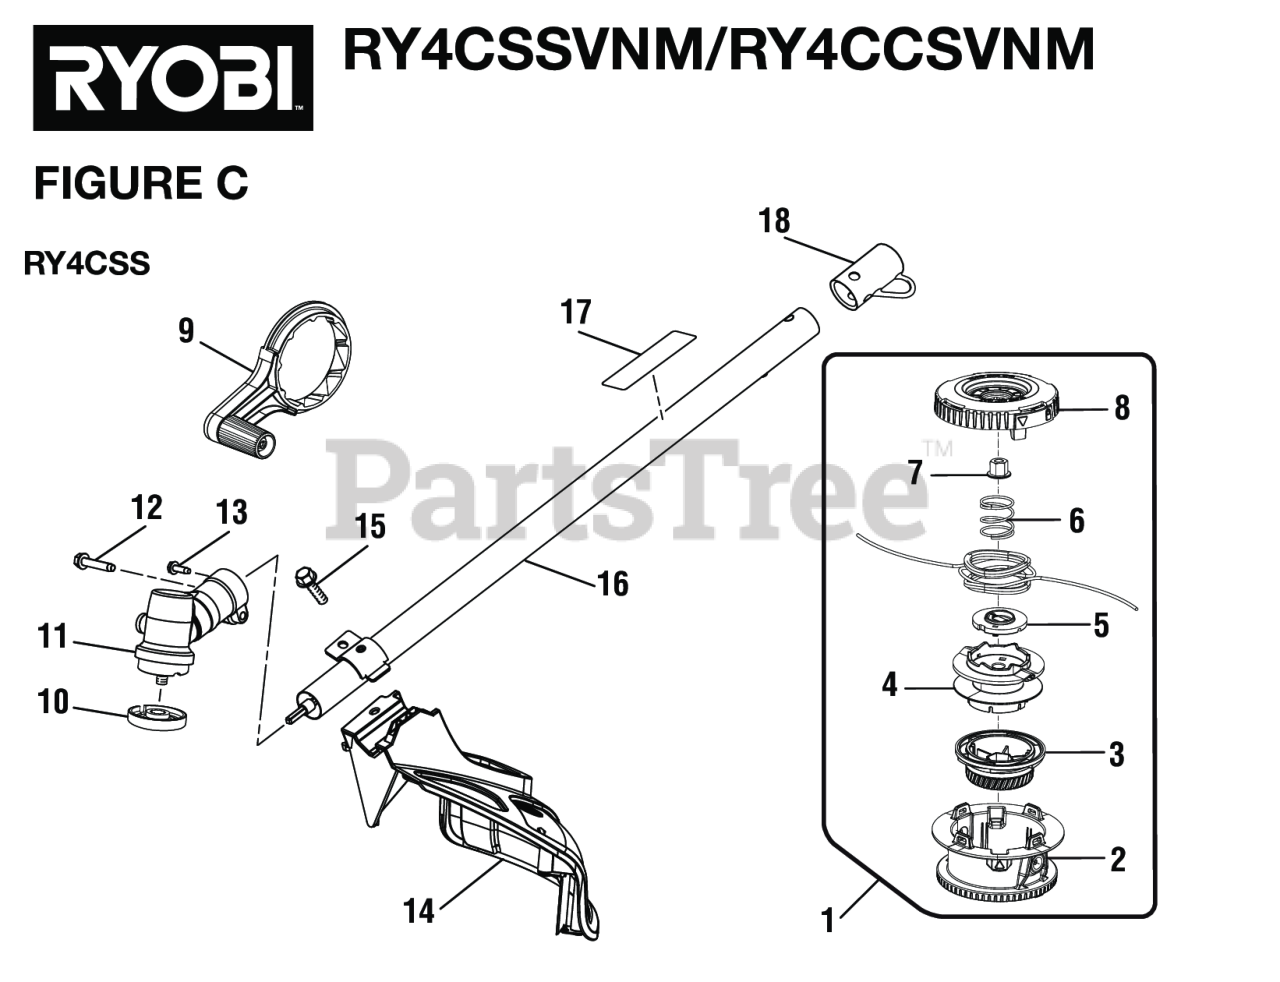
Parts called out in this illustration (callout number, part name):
1	Trimmer Head Assembly (.095) (Inc. Key Nos. 19-25)
2	Bump Head
3	Bump Knob (Green)
4	Spool Assembly
5	String Guide
6	Compression Spring
7	Hex Nut (M8, Left Hand Threads)
8	Locking Assembly
9	Crank Handle
10	FLANGED WASHER
11	Gear Head
12	Screw (1/4-20 x 1-1/4 in., Hex Washer Hd. S.T.)
13	Screw w/Washer (10-24 x 5/8 in., Hex Hd. T.F.)
14	Grass Deflector Assembly
15	SCREW (#1/4-20 X 1-1/4 in. HEX WASHER HD.)
16	Straight Shaft Assembly (Inc. Key Nos. 17-18)
17	Warning Icon Label
18	Storage Hanger Cap
